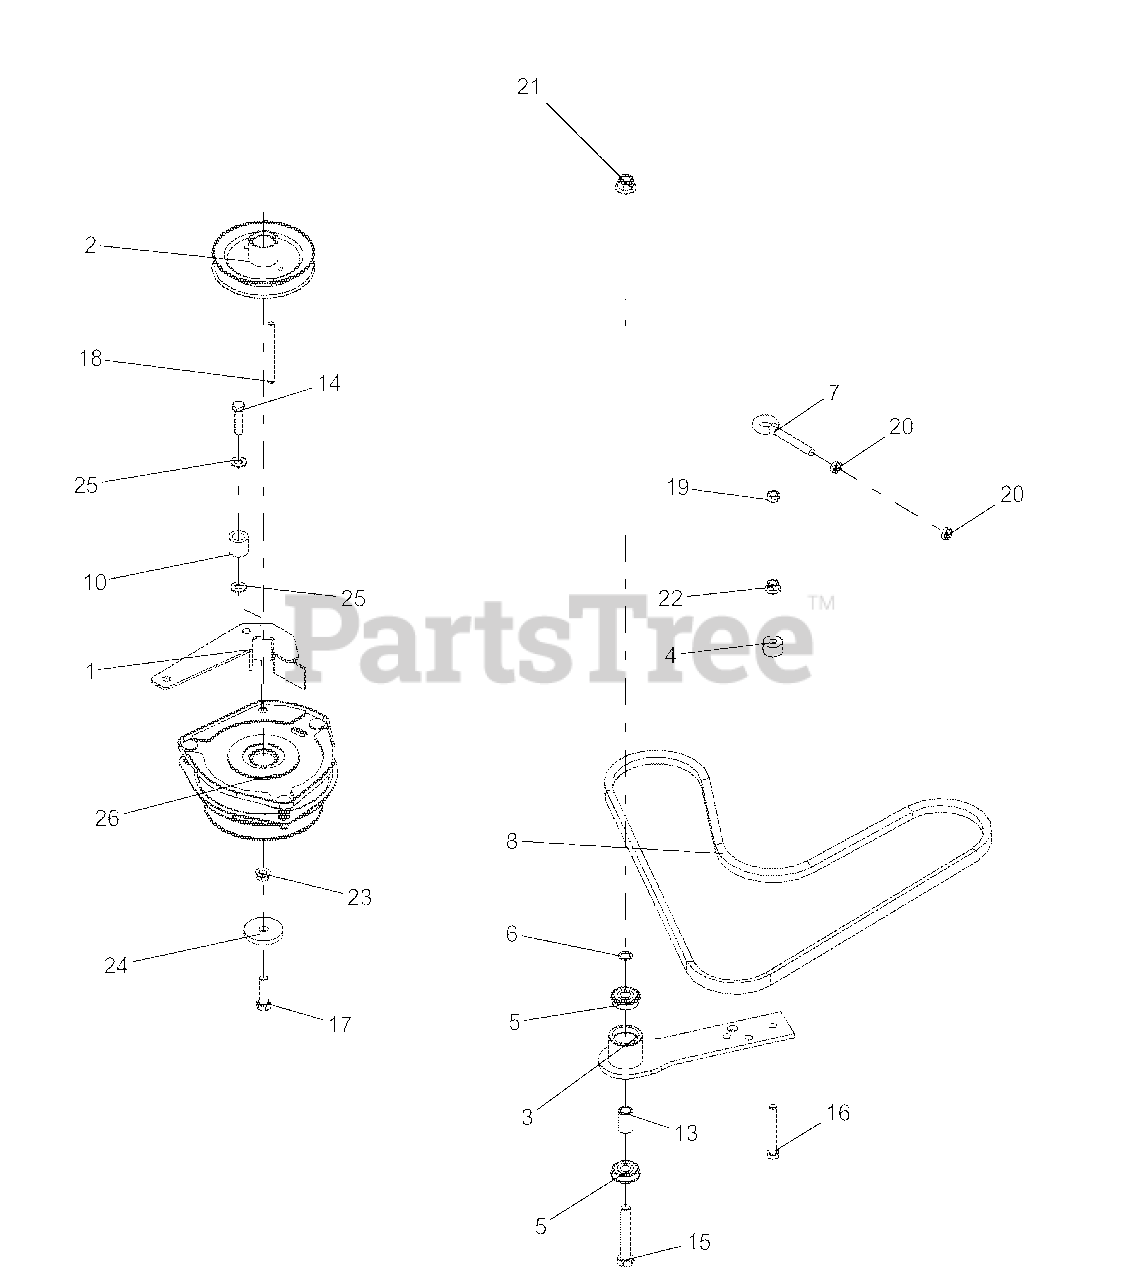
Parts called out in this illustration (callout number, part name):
1	WMT, CLUTCH STOP - BLACK
2	SHEAVE, ENGINE 1.127 ID X 5.250 OD-BLACK
3	WLDMT, HYDRO DRIVE IDLER ARM-BLACK
4	SPACER .390X1.000X.562
5	BRG, BALL .501 X 1.38 X .438 SEALED
6	WASHER-FLAT-STL, .500 X .750 X .020
7	BOLT, EYE .375-16
8	BELT, B RAW COGGED
10	BUMPER, RUBBER .62 X 1.0 X .88 LG
13	SPACER, .510 X .750 X 1.148
14	BLT-HEX .38-16X1.50 GR5 YWZC
15	BLT-HEX .50-13X3.00 GR5 YWZC
16	BLT-HEX .38-16X2.75 GR5 YWZC
17	BLT-HEX .44-20X1.50 GR8 YWZC
18	KEY-SQ .250X.250X3.50
19	NUT-LK-CTR .38-16 YWZC
20	NUT, JAM .375-16 YWZC
21	NUT-LK-NYL-FLG .50-13 YWZC
22	NUT-LK-NYL-FLG .38-16 YWZC
23	NUT, LK-TOP-FLG .38-16 YWZC
24	WSHR-FL-STL .469X2.00X.25 YWZC
25	WSHR-FL-STL.406X.812X.065 YWZC
26	CLUTCH-OGURA
